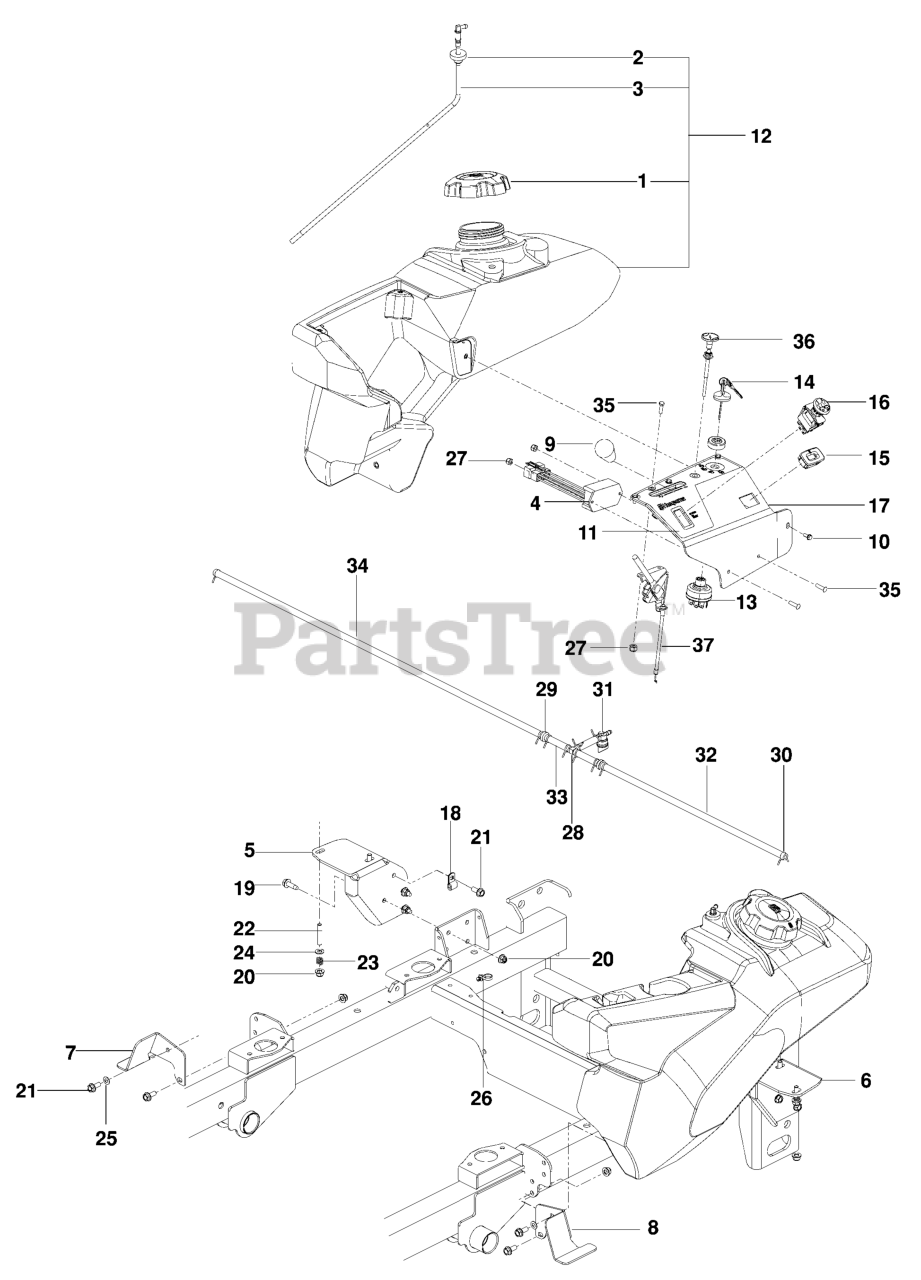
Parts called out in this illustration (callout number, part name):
1	FUEL CAP, HTC
2	RUBBER GROMMET
3	FITTING, FUEL
4	TIMER, SEAT
5	MOUNT, RT TANK, BLK
6	MOUNT, LT TANK, BLK
7	MOUNT, TANK, RT
8	MOUNT, TANK, LT
9	KNOB - SHIFT
10	SCR #10-24 X 3/8 SKT HD BLK OX
11	DECAL, CONTROL, GAS
12	FUEL TANK ASM RT
13	RB SWITCH, KEY EARLY PZ ONLY
14	KEY, IGNITION
15	HOUR METER
16	SWITCH, PTO 10 AMP
17	PANEL.CONTROL.GAS.GRAY
18	DOUBLE TUBE CLAMP
19	RP BLT 5/16-18 X 1 THRD FORM D
20	5/16-18 NYLOC FLANGE NUT
21	HHFS 5/16-18 X 3/4
22	STUD, 5/16C
24	FLAT WASHER 5/16 SAE
25	WASH 5/16 DISC SPRING ZD
26	TIE WRAP, 8-3/8", W/CLIP
27	NUT 10-24 NYLOC
28	TEE, FUEL LINE, .25
29	VALVE, CHECK, .25
30	HOSE CLAMP
31	FUEL VALVE
33	FUEL LINE 3"
35	SCR #10-24 X .75 SKT HD BLK
36	CABLE, CHOKE, 48"
37	CABLE, THROTTLE, 60"
